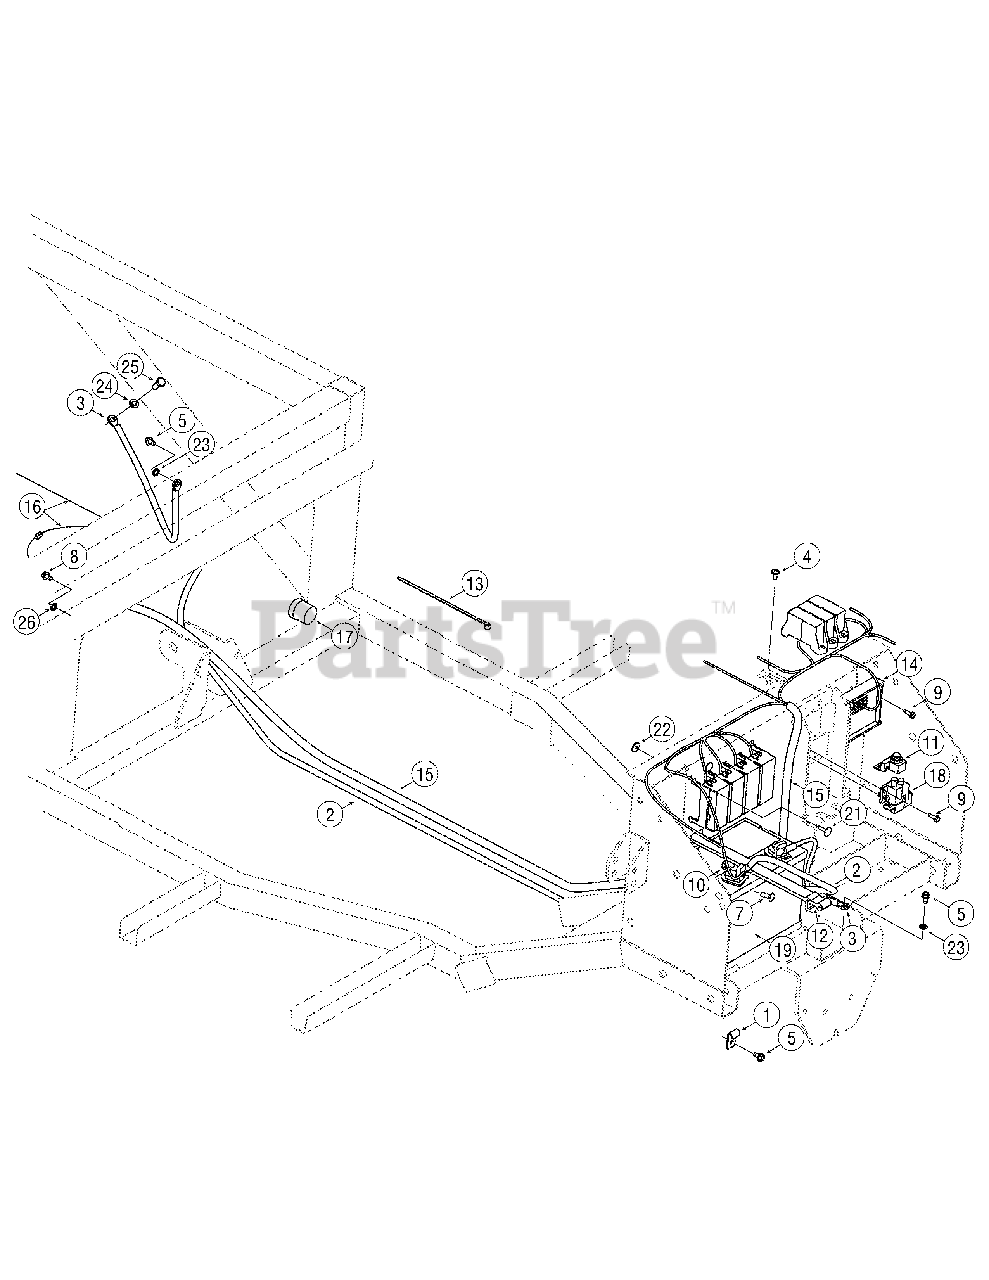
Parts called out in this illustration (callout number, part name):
1	Bracket, Retainer Hook
2	Harness Assembly, Starter
3	Harness Assembly, Ground
4	Screw, 1/4-20 x .50
5	Screw, Self-tapping, 1/4-20 x 0.500
6	Screw, Self-tapping, 5/16-18 x .50
7	Screw, Hex Carriage, 1/4-20 x .75
8	Screw, Self-tapping, 1/4-20 x 1.000
9	Screw, #10-32 x 0.625
10	Nut, Hex Sems, 1/4-20
11	Cover, Protective
12	Strap, Battery
13	Cable Tie, 3/16 x .05 x 7.4
14	Control, Shaft
15	Harness, Utility Main
16	Harness Assembly, Motor, Kohler
17	Control, Reverse
18	Switch
19	Battery
21	Rivet, Pop
22	Washer, Flat, .194 x .62 x .063
23	Washer, Lock, 1/4
24	Washer, Lock, 5/16
25	Screw, M8-1.25
26	Washer, Lock, 1/4
